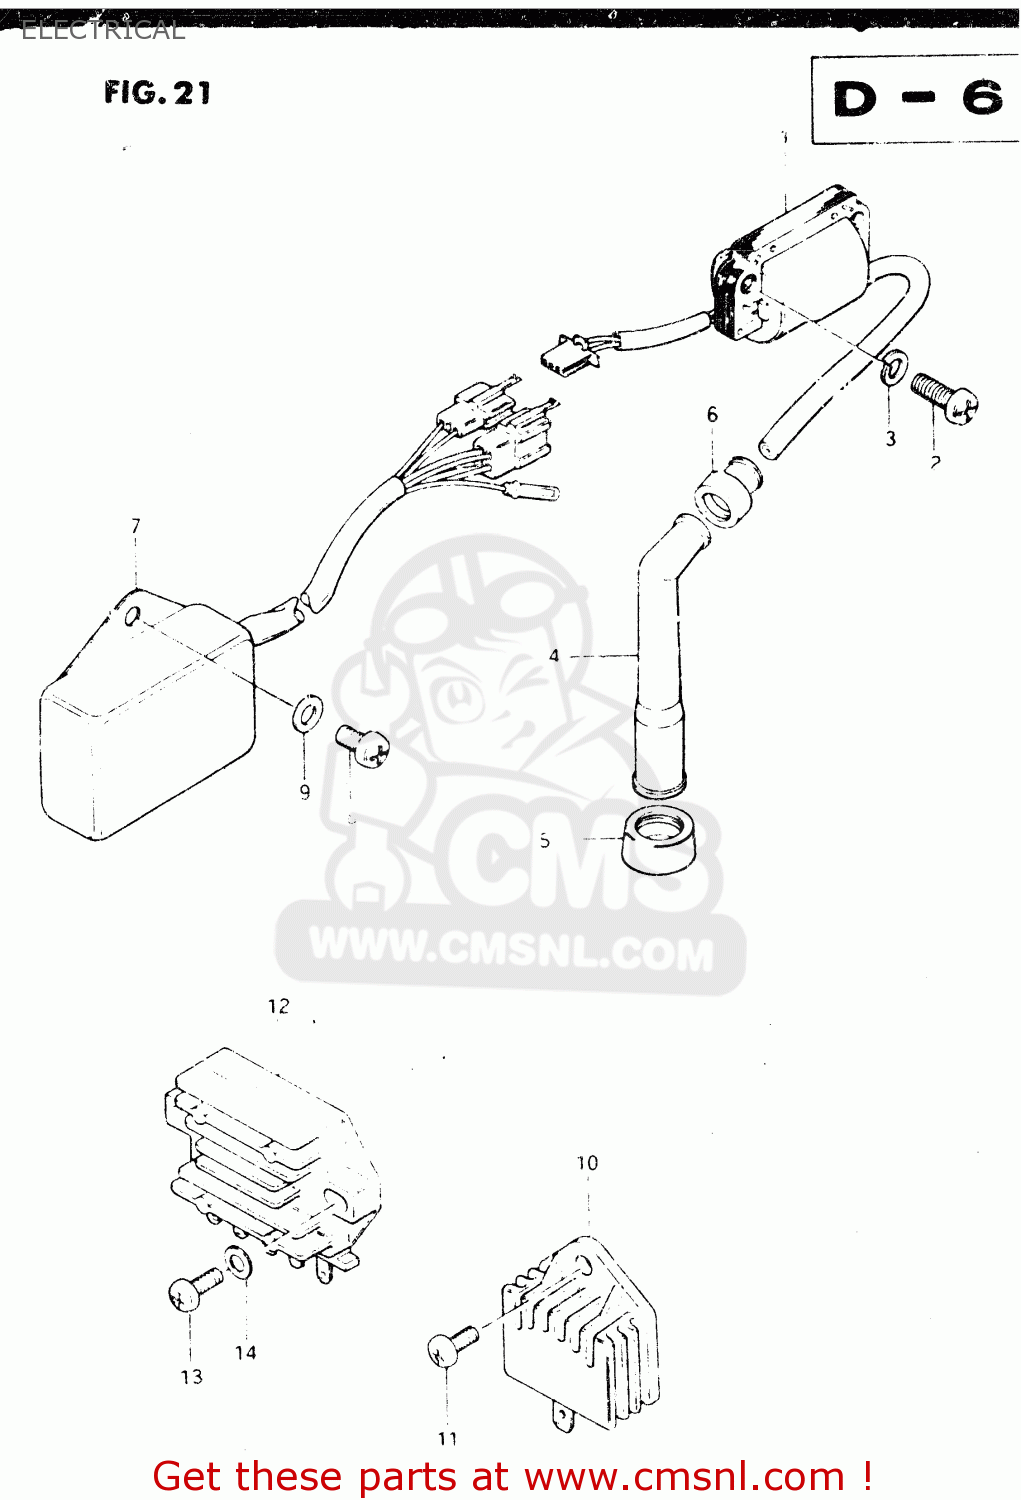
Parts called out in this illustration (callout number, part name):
1	COIL ASSY,IGNITION
2	SCREW
3	LOCK WASHER
4	CAP ASSY,SPARK PLUG
5	SEAL,SPARK PLUG
6	SEAL,SPARK PLU
7	IGNITER UNIT
8	SCREW
9	WASHER
10	RECTIFIER ASSY,REGULATOR
11	SCREW 6X12
12	RECTIFIER ASSEMBLY
13	SCREW
14	WASHER
